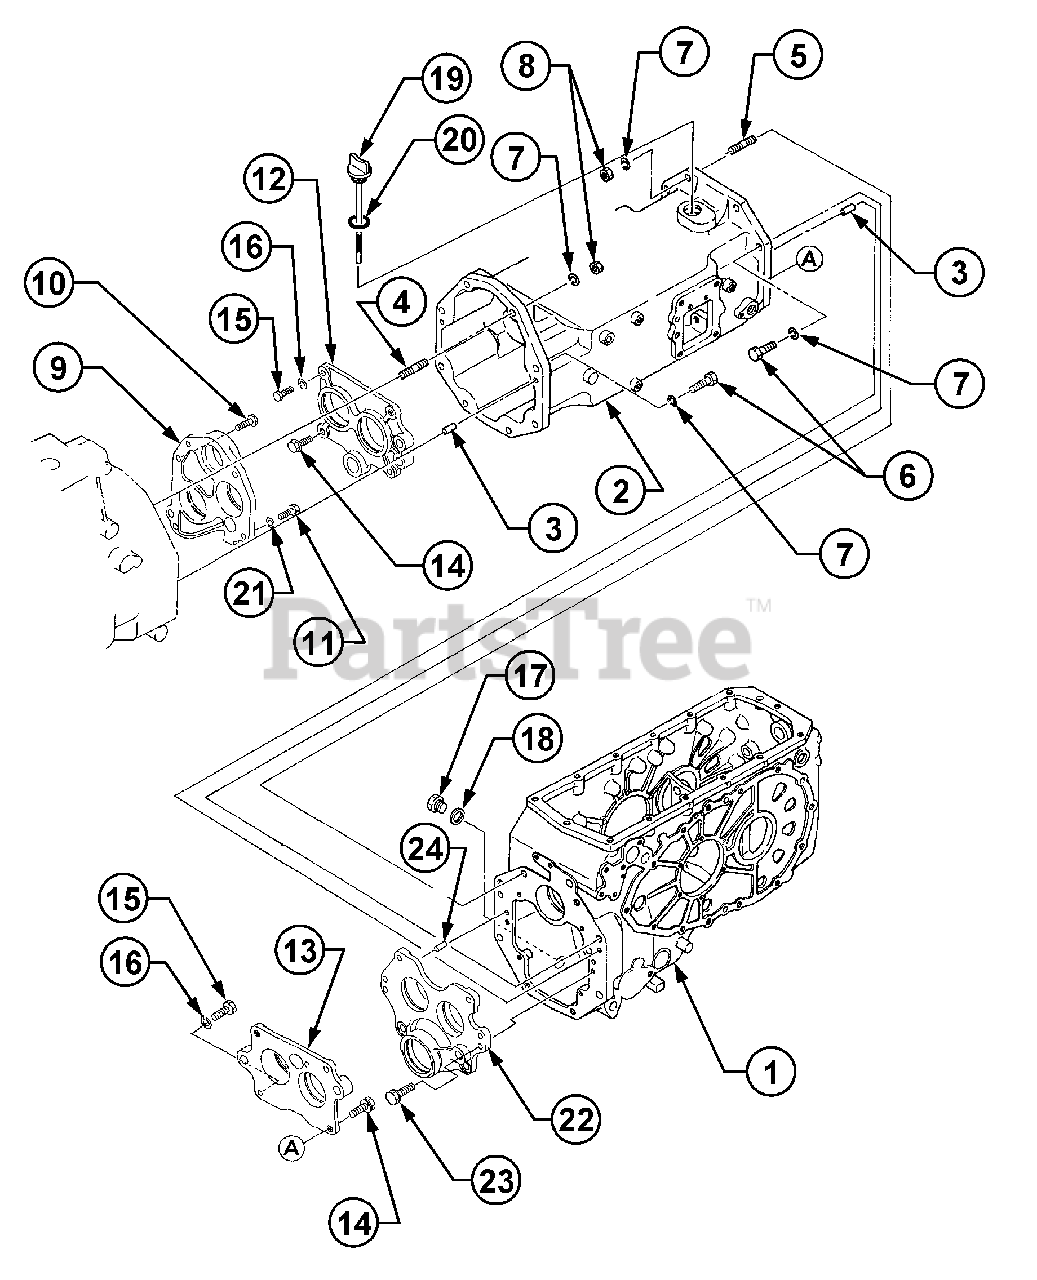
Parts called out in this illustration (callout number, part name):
2	Case, Center
6	Bolt
7	Washer, Spring
10	Bolt, w/Washer
14	Bolt, w/Washer
16	Washer, Spring
19	Plug, Oiling
21	Washer, Spring
23	Bolt, w/Washer
